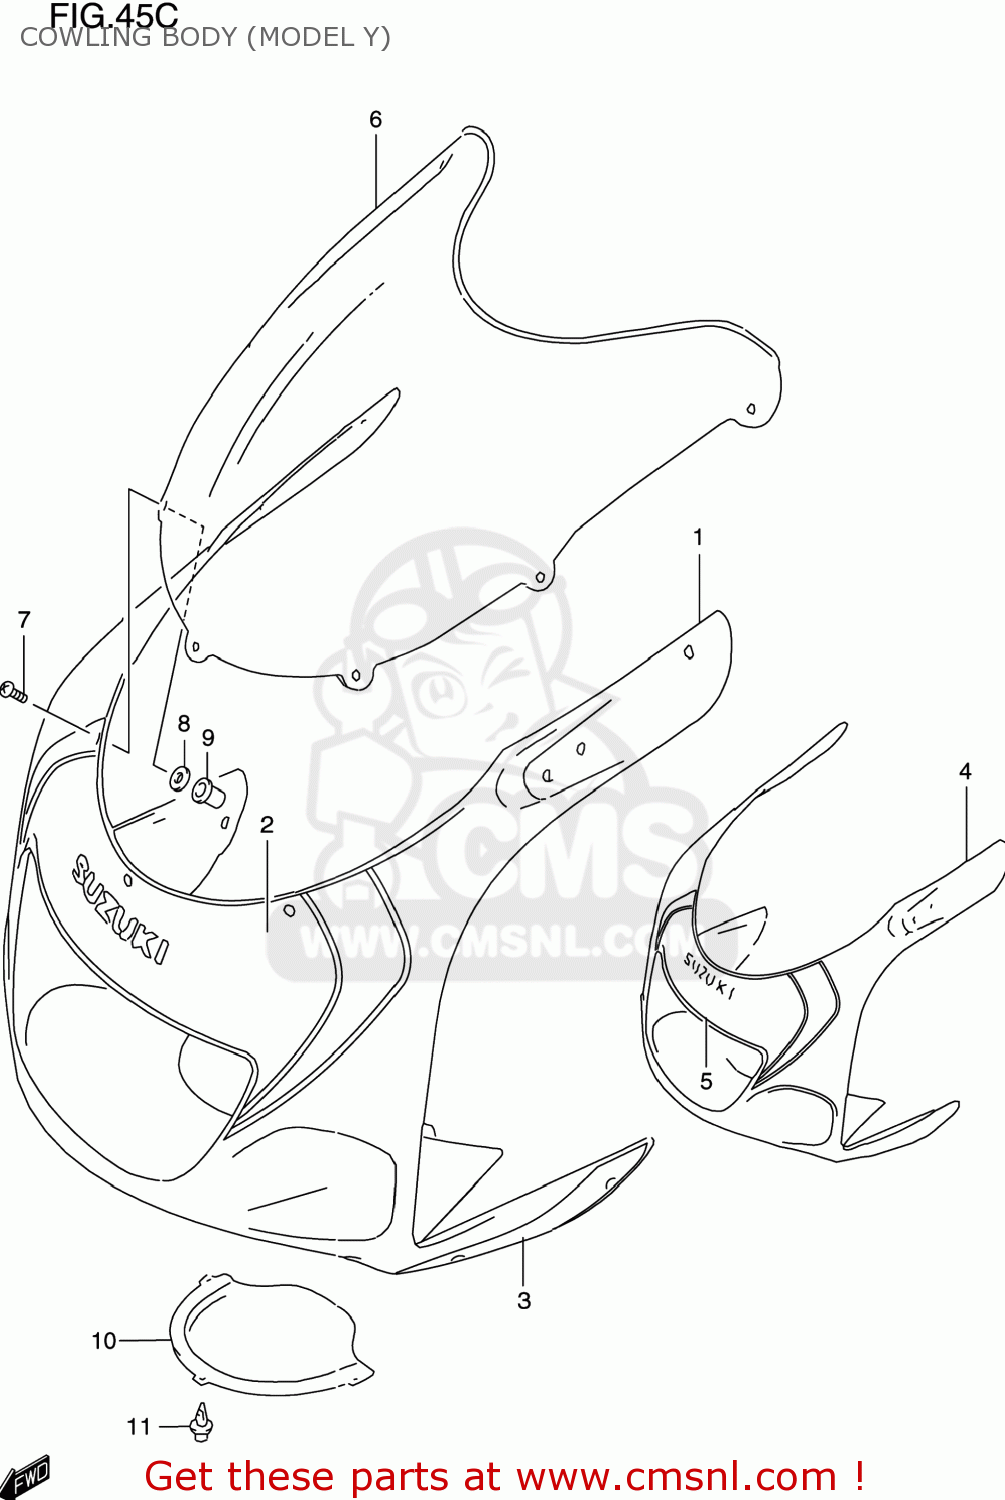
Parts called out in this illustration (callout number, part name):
1	COWLING ASSY,BODY
2	TAPE SET,COWL BODY FR
3	TAPE SET,COWL BODY SIDE
4	COWLING ASSY,BODY
5	TAPE SET,BODY,FRONT
6	WINDSCREEN
7	SCREW(5X14)
8	WASHER
9	NUT
10	LID,BODY COWL LWR
11	CLIP(BLACK)
